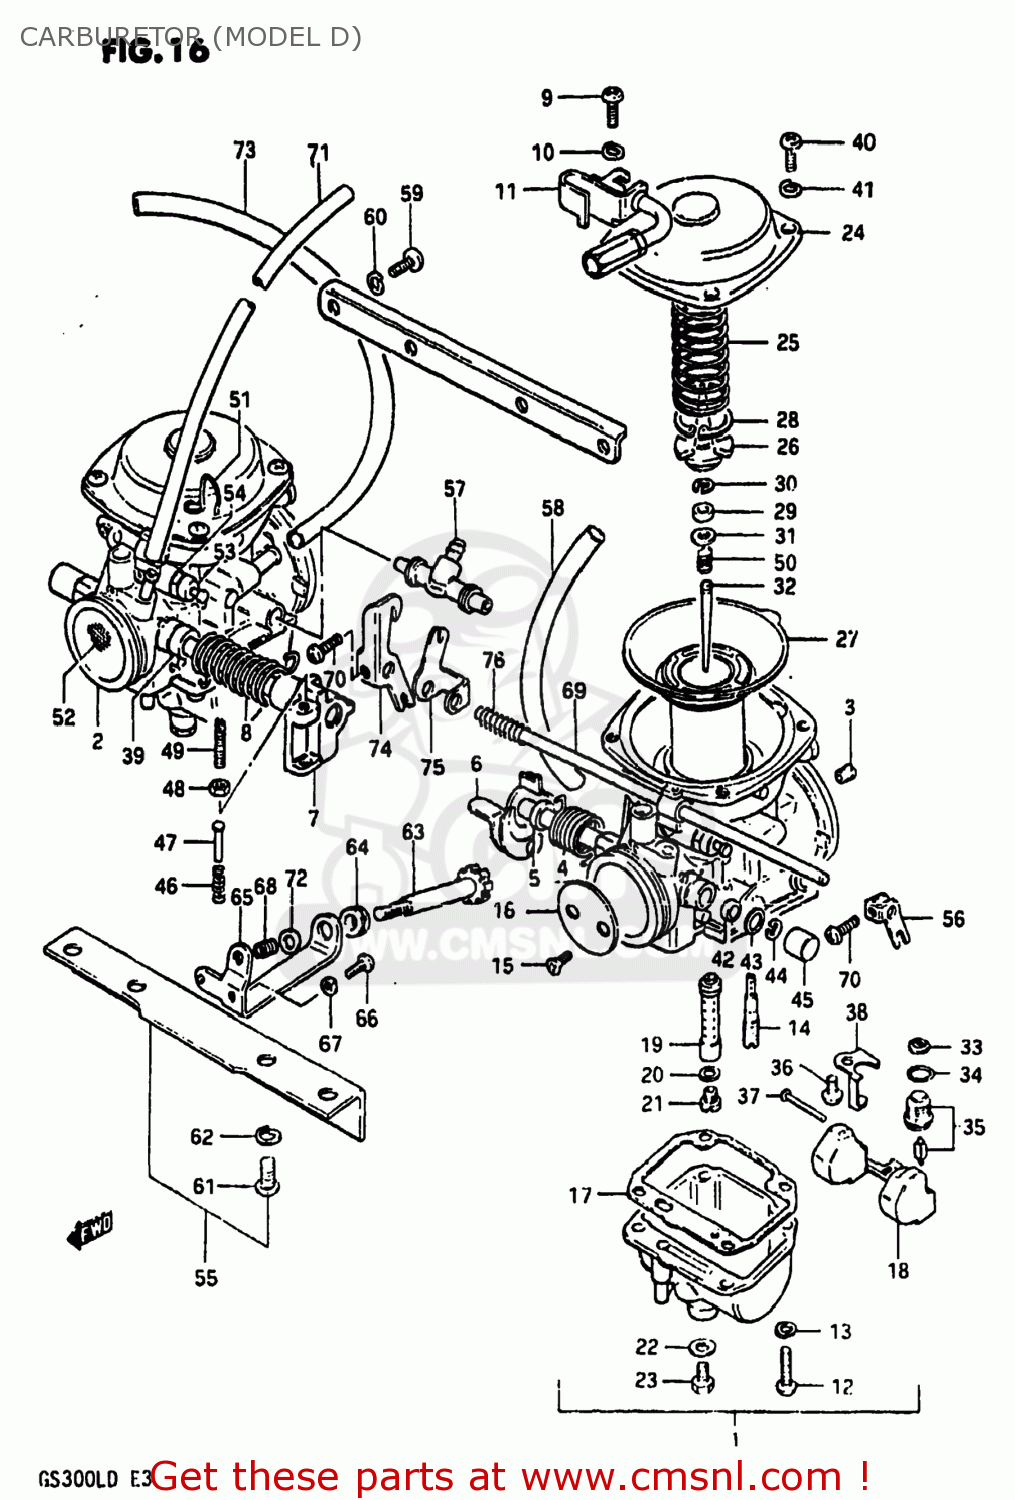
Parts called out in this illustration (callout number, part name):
1	CARBURETOR ASSEMBLY
2	CARBURETOR ASSEMBLY,RIGHT (BS
3	JET,MAIN
4	SPRING
5	RING
6	SHAFT ASSEMBLY
7	SHAFT ASSEMBLY
8	SPRING
9	SCREW
10	LOCK WASHER
11	BRACKET,THROTTLE CABLE
12	SCREW
13	LOCK WASHER
14	JET,PILOT(17.5)
15	SCREW
16	VALVE,THROTTLE
17	GASKET,FLOAT CHAMBER (NAS)
18	FLOAT
19	JET,NEEDLE
20	WASHER,NEEDLE NOZZLE
21	JET,MAIN(115)
22	GASKET (NAS)
23	PLUG,DRAIN
24	COVER,DIAPHRAGM
25	SPRING
26	HOLDER,GUIDE
27	DIAPHRAGM
28	E RING
29	RING
30	CLIP,NEEDLE
31	WASHER
32	NEEDLE JET
33	FILTER
34	O RING
35	VALVE ASSEMBLY,NEEDLE
36	SCREW 4X6
37	PIN,FLOAT
38	PLATE,NEEDLE VALVE FITING
39	RING,THROTTLE VALVE
40	SCREW
41	LOCK WASHER LH:3, RH:4
42	SEAL
43	GASKET,THROTTLE SHAFT (NAS)
44	E RING
45	CAP
46	SPRING,THROTTLE SCREW
47	PIN,THROTTLE LEVER
48	NUT
49	SCREW
50	SPRING
51	CLIP,HOSE
52	FILTER NET ASSEMBLY
53	CAP,PLUNGER
54	O-RING
55	CARBURETOR ASSEMBLY
56	LEVER
57	NIPPLE,CARBURETOR
58	HOSE
59	SCREW
60	LOCK WASHER
61	SCREW
62	LOCK WASHER
63	SCREW,THROTTLE STOP
64	BUSHING,THROTTLE ADJUSTER
65	BRACKET
66	SCREW
67	LOCK WASHER
68	SPRING
69	SHAFT,STARTER
70	SCREW,THROTTLE ADJUST
71	HOSE
72	WASHER
73	HOSE
74	LEVER,STARTER
75	SPACER,STARTER LEVER
76	SPRING
